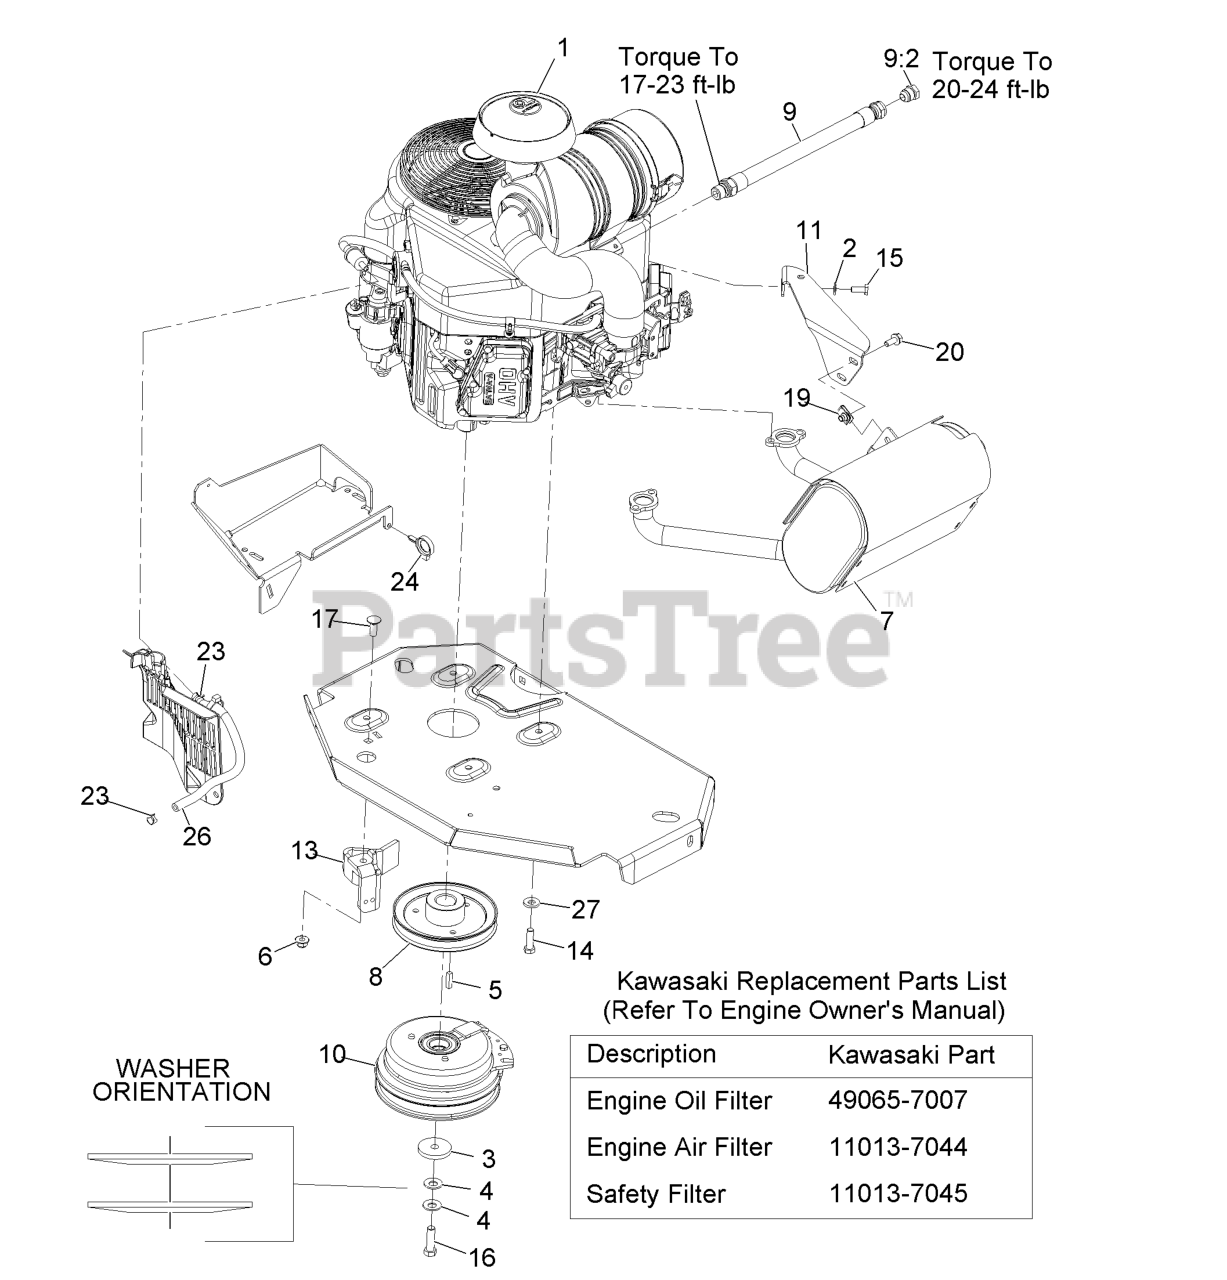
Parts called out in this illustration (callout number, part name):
2	WASHER-SPRING
3	WASHER-CLUTCH
4	WASHER-SPRING
6	NUT-HF, NI
7	MUFFLER
8	SHEAVE
10	CLUTCH KIT
11	BRACKET-MUFFLER
13	CLUTCH-ANCHOR
14	SCREW-HH
15	SCREW-HH
16	SCREW-HH 7/16-20 X 1 1/2 W/LOCTITE
17	SCREW-CARR
20	SCREW-HHF
23	CLAMP-HOSE
24	CLAMP-HOSE
26	HOSE-FUEL
27	WASHER-BELLEVILLE
